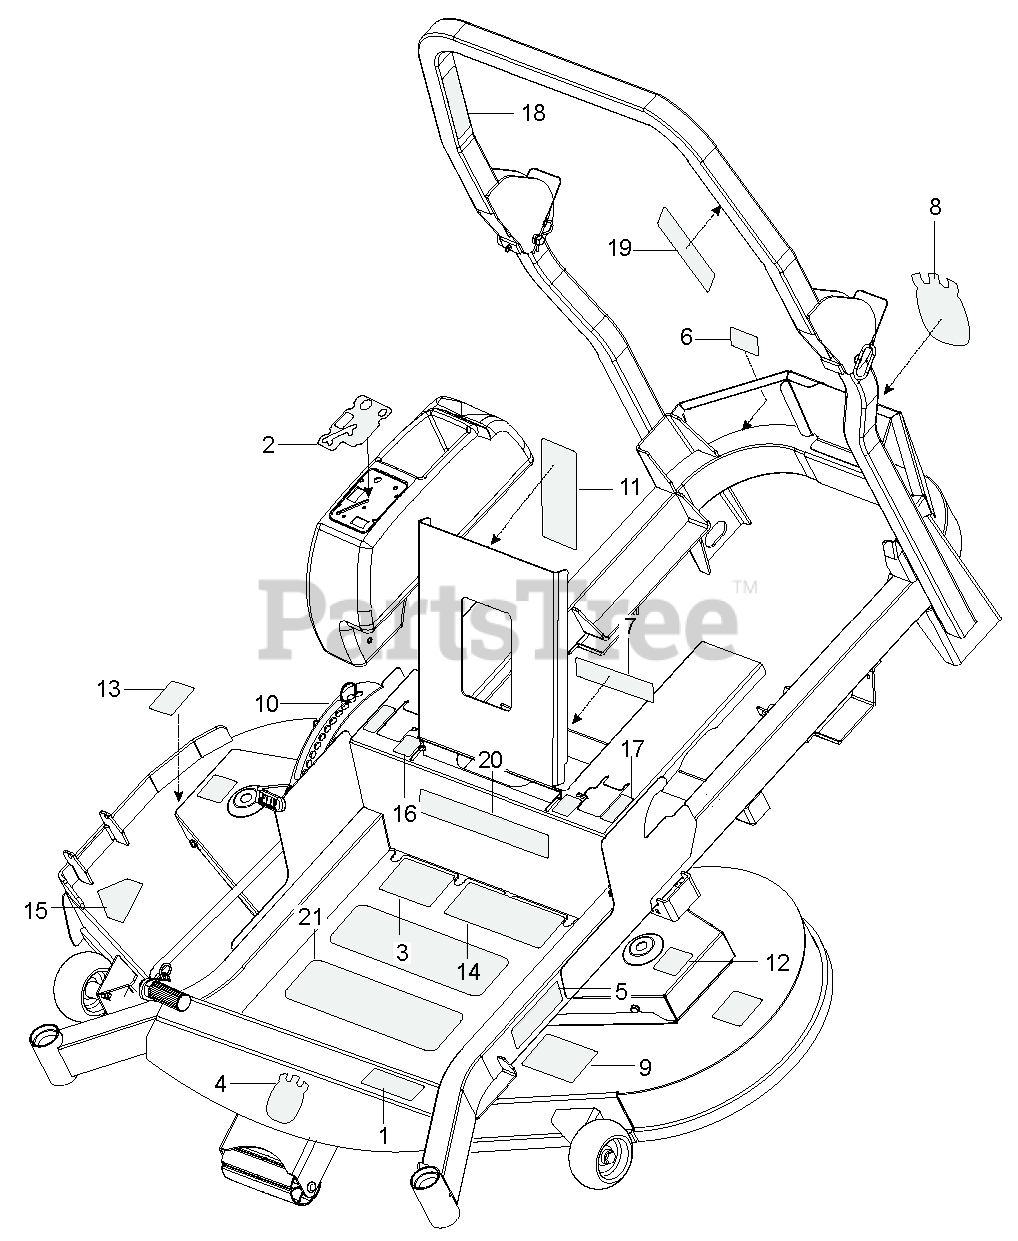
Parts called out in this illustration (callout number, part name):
1	DECAL.ZTR.MZ61.HUSQ
2	DECAL, CONSOLE HUS
3	DECAL.ZTR.STRTNGINST.REMOTECHK
4	DECAL.AUGER.HUSQ.CROWN.SNOW
5	RP.DECAL.BADGE.170MM.TEXTLOGO
6	DECAL, BELT DRIVE
7	EURO DECAL-BATTERY WARNIN6
8	DECAL, CROWN H, 110MM
9	DECAL, BELT ROUTING
10	DECAL, HEIGHT ADJUST
11	DECAL, SERVICE
12	DECAL.DECK.6MIL.EURO.NOSTEP
13	DECAL.DECK.6MIL./DEF.SHLD.WARN
14	DECAL ZTR WARNING DECAL DECAL.
15	DECAL, DECK DEFLECTOR, WARNING
16	DECAL.STR.S.T.SYSMBOLONLY.2014
17	DECAL.ZTR.MZ61.HUSQ
18	DECAL, ROPS, WARNING
19	DECAL ROPS
20	DECAL ZTR BRAND GRAPHIC DECAL.
21	ANTI-SKID PAD
